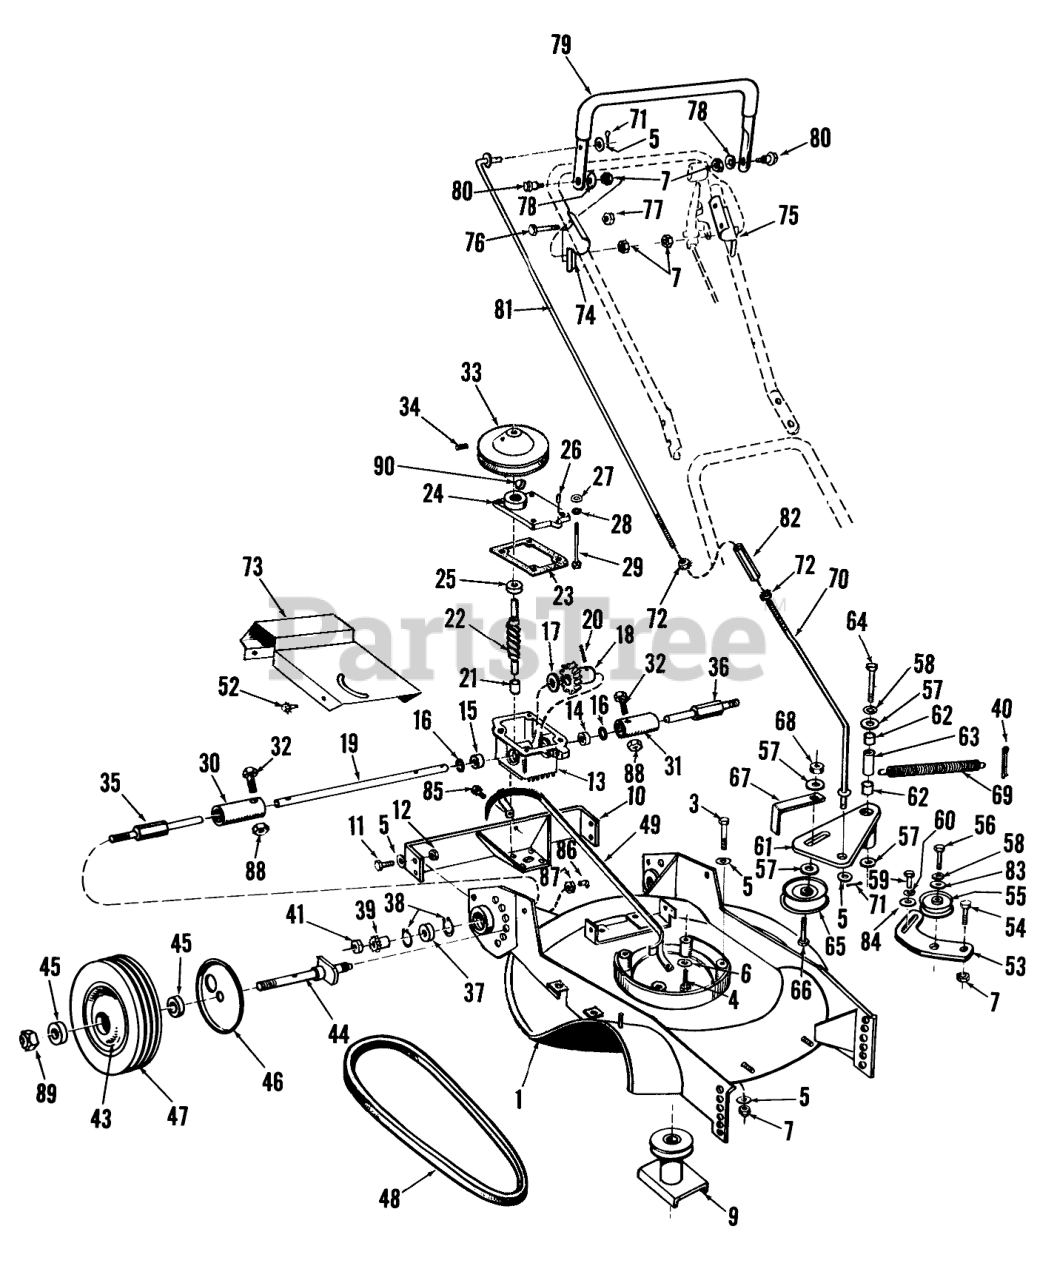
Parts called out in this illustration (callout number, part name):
1	Housing
3	SCREW-HH
4	SCREW-HH
5	WASHER-PLAIN
6	WASHER-LOCK
7	Nut
9	Blade Retainer
10	Support, Gear Case
11	SCREW-HH
12	NUT-LOCK NI
13	Gear Case (Incl. (1) Ref.14, (1) Ref.15 & (1) Ref.21
14	Bushing
15	Bushing
16	Seal
17	THRUST WASHER
18	WORM GEAR
19	GEAR BOX SHAFT
20	5/32 X 7/8 ROLL PIN
21	.437 NEEDLE BEARING
22	WORM SHAFT
23	GASKET
24	Cover Gear Box
25	Bearing
26	3/16 X 1/2 ROLL PIN
27	WASHER-FLAT
28	WASHER-LOCK
29	SCREW-HH
30	R/H CLUTCH HSG ASM
31	L/H CLUTCH HSG ASM
32	DRIVE SCREW
33	GEAR BOX PULLEY
34	SCREW-HSH
35	OUTPUT SHAFT
36	OUTPUT SHAFT
37	.375 RPP BALL BEARING
38	1-1/8X056 IN SNP RING
39	Pinion Kit
40	PIN-COTTER
41	NUT-HJ
43	Drive Wheel Assy. (Incl. (2) Ref.45 Bearings)
44	Spindle (Incl. Ref. #21)
45	BEARING-BALL
46	WHEEL COVER
48	V-BELT
49	Belt Guide
53	Arm, Auxiliary Idler
54	SCREW-HH
55	PULLEY-IDLER
56	SCREW-HH
57	WASHER-FLAT
58	WASHER-LOCK
59	SCREW-HH
60	WASHER-LOCK, INTERNAL
61	Idler Arm (Incl.(1) Ref.62)
62	BUSHING
63	ROLLED SPACER
64	SCREW-HH
65	IDLER PULLEY R
66	Screw
68	Nut
69	IDLER SPRING
70	CONTROL ROD
71	PIN-COTTER
72	NUT-KEPS
73	Shroud
74	CONTROL BAIL BRACKET
75	Bracket-Control Bail
76	10-24X1-1/4 PAN HD MS
77	NUT-LOCK, NI
78	WASHER-SPRING
79	Control Bail
80	SCREW-SHOULDER
81	Control Rod
82	CONTROL ROD SLEEVE
83	WASHER-FLAT
84	WASHER-PLAIN
85	Screw
86	GREASE FITTING
87	NUT-LOCK, NI
88	NUT-LOCK, NI
89	Nut
90	3/32X5/8 WOODRUFF KEY
